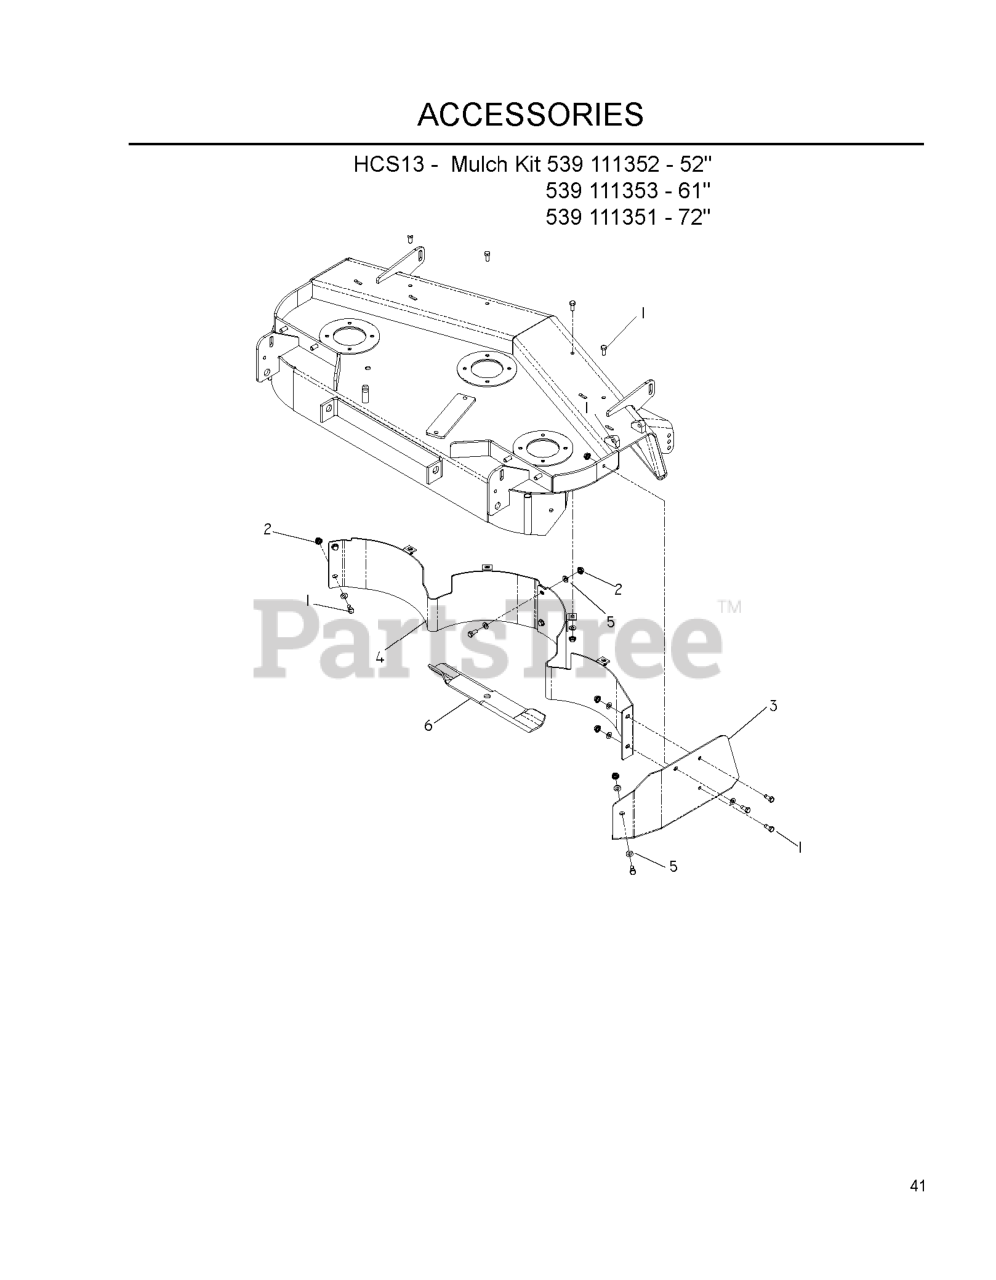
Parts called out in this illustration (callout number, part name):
1	HCS 5/16C X 3/4
2	NUT 5/16C WHIZ
3	BAFFLE WLDMT, 52" R.H. MULCH
4	BAFFLE WLDMT, 52" L.H.
5	FLAT WASHER 5/16 SAE
6	BLADE MULCH 18"
7	MULCH CAP 52
